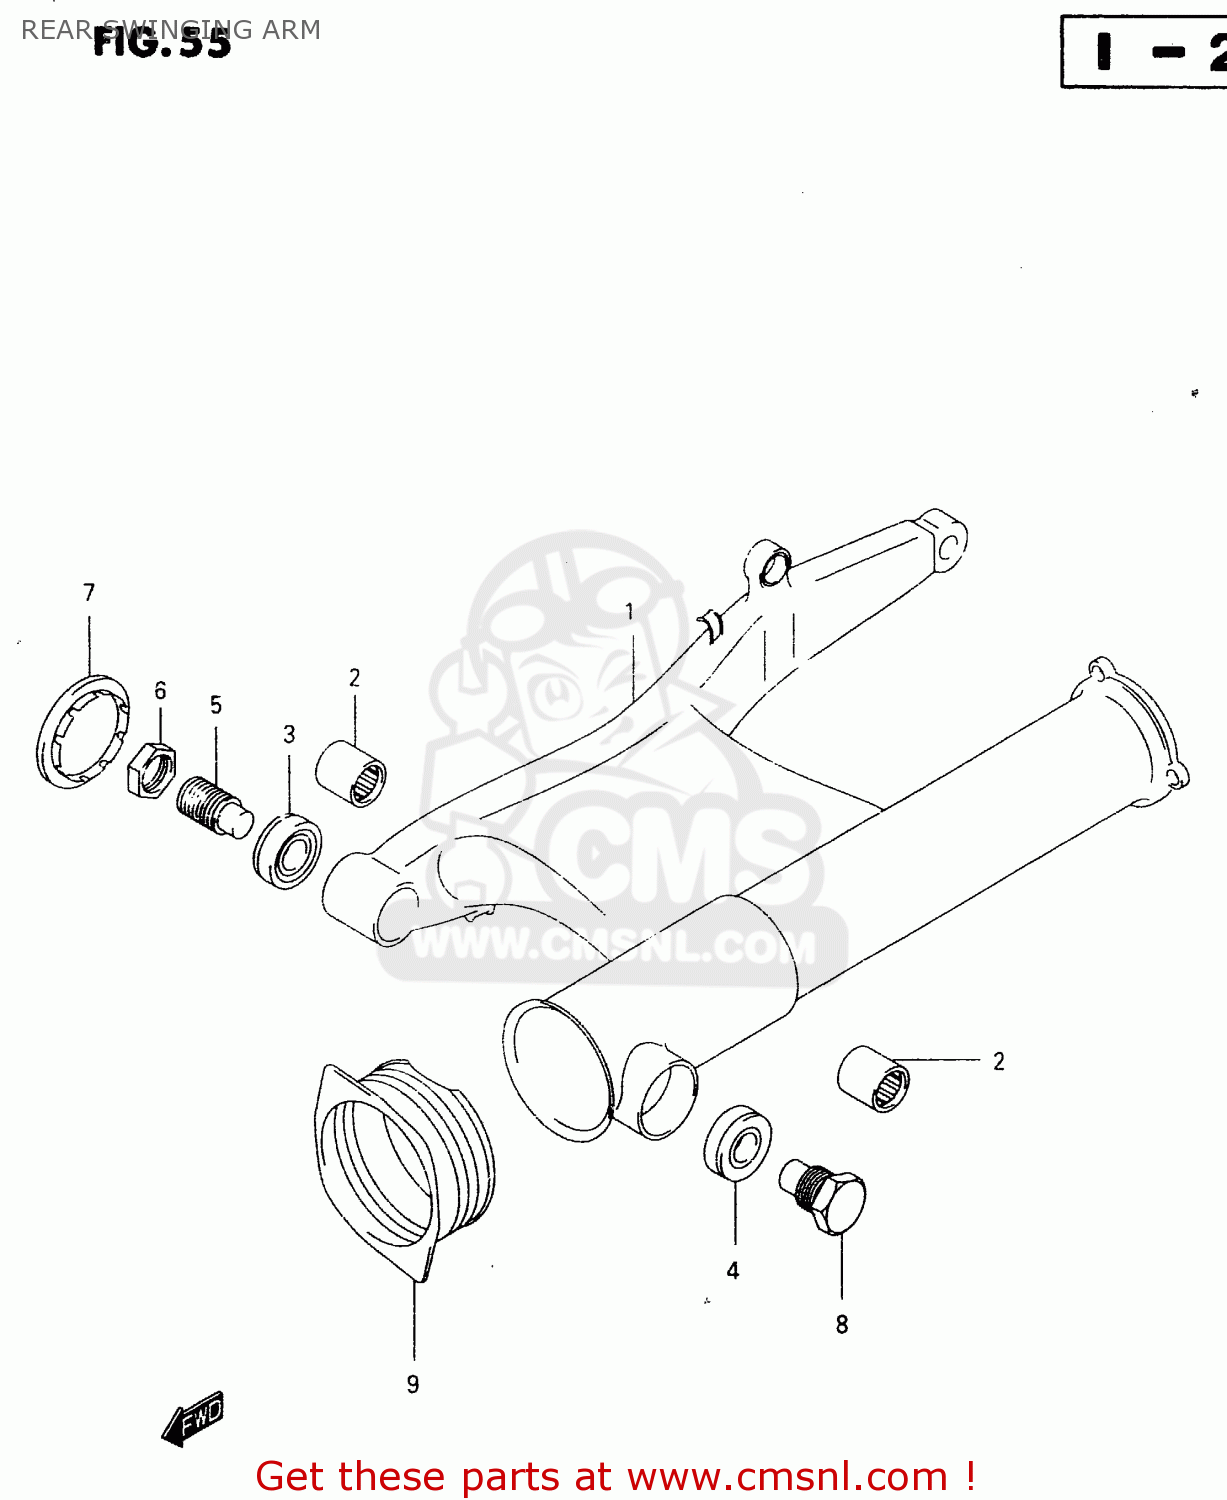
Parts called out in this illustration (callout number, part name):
1	SWING ARM COMP,REAR
2	BEARING(20X27X23.5)
3	BEARING(17X40X13.25)
4	BEARING(17X40X13.25)
5	BOLT,RR SWGARM PIVOT
6	NUT
7	CAP,RR SWINGING ARM PIVOT NUT
8	BOLT,SWINGINGARM PIVOT,L
9	BOOT,PROPELLER SHAFT
